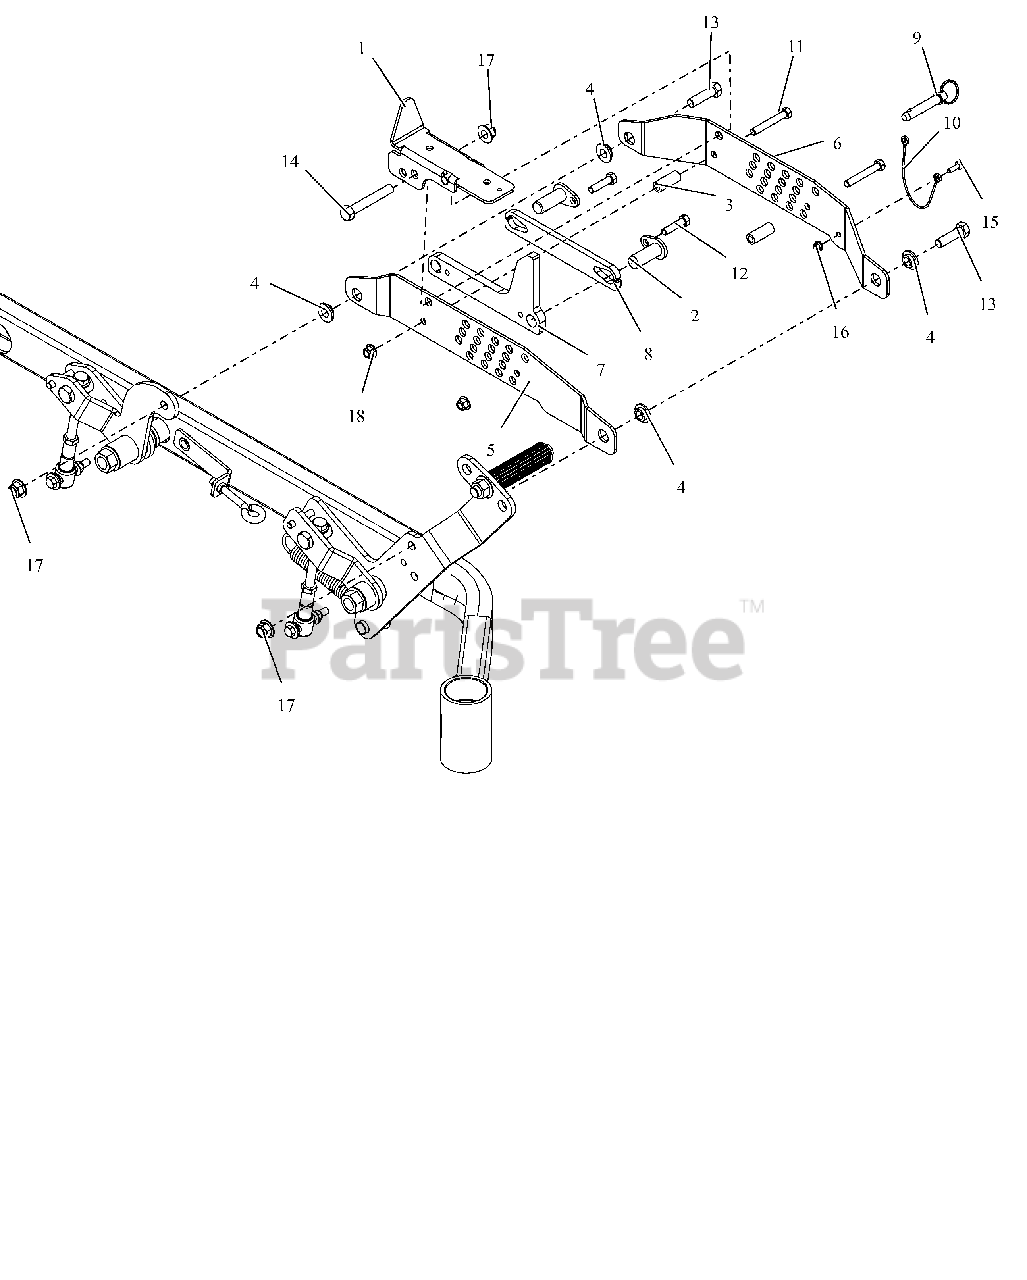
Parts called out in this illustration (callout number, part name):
1	MECHANICAL LOCK-UP WMT - BLACK
2	WLDMT, PIN HOC MOUNTING
3	SPACER, .375 X .625 X 1.54
4	BSHG-FLG .515X.750X.310X1.120
5	RH OTBRRD LIFT/CUT HT BRKT-BLK
6	RH INBRD LIFT/CUT HT BRKT- BLK
7	HOC STOP BRKT - BLK
8	HOC STOP SPACER - BLK
9	PIN, .50 X 2.00 USABLE LG BALL
10	CABLE, 12.0 LANYARD, NYLON
11	BLT, HEX .38-16X2.50 G5 ZCC
12	BLT, HEX 0.375-16X1.5 GR5 ZCC EP30
13	BLT, HEX .50-13X1.75 G5 ZCC
14	BLT,HEX .50-13X3.25 G5 ZCC
15	BLT, HEX .25-20X.75 G5 ZCC
16	NUT,NYL-FLG .25-20 GF ZCC
17	NUT,NYL-FLG .50-13 GF ZCC
18	NUT,NYL-FLG .38-16 GF ZCC
